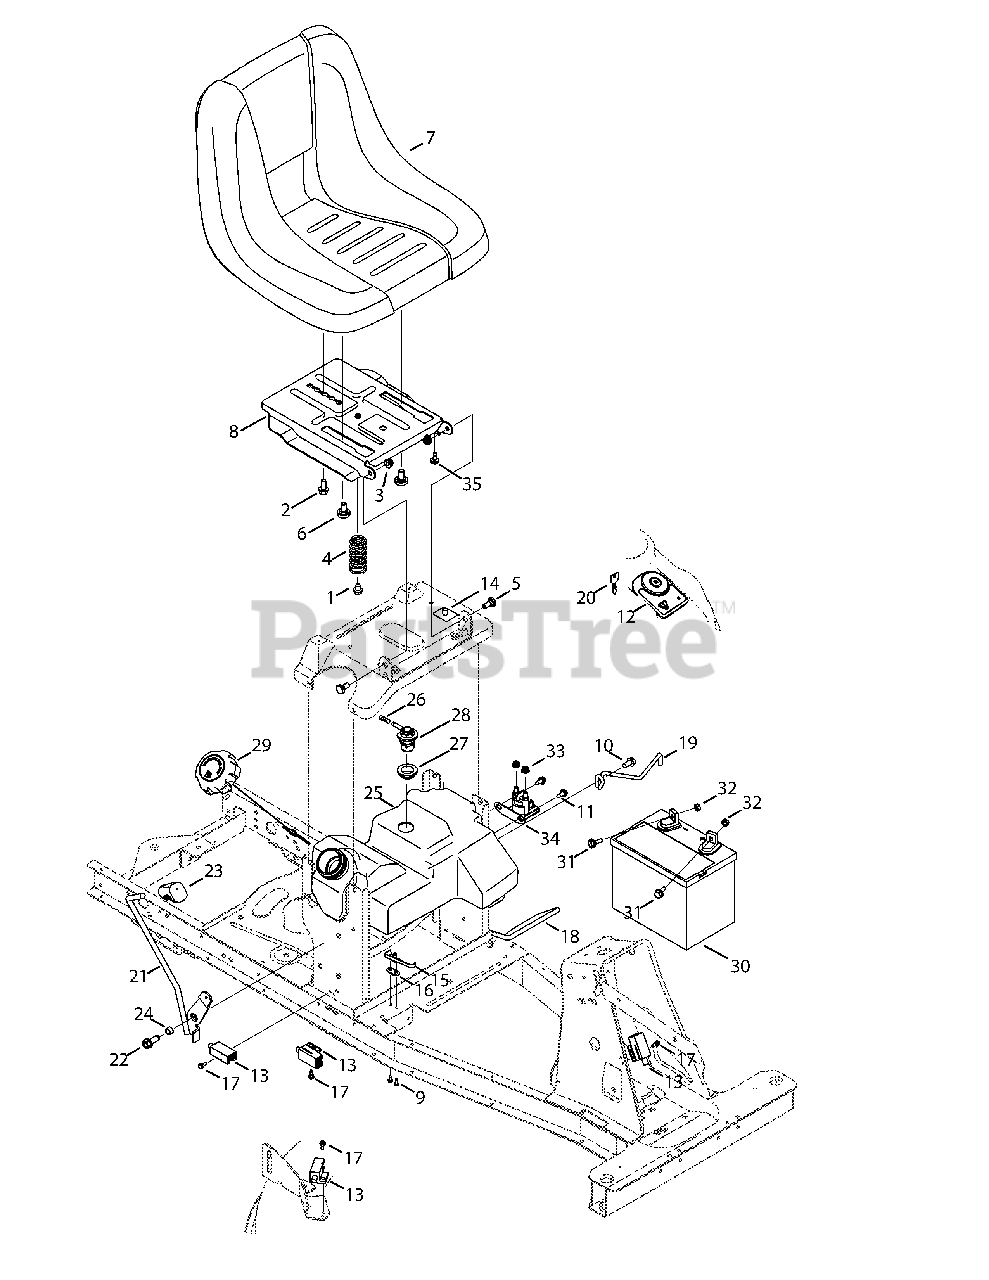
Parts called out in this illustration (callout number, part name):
1	Tap Screw, 5/16-18, 0.500
2	Hex Flange Screw, 3/8-16 x .75
3	Flange Lock Nut, 5/16-18
4	Seat Spring
5	Shldr Spacer, .435 X .178-5/16 X .56
6	Shoulder Screw, .625 x .145, 3/8-16
8	Seat Pivot Bracket
9	Screw, #8
10	Tap Screw, 5/16-18, .750
11	Tap Screw, 1/4-20, .625
12	Key Switch
13	Interlock Switch
14	Seat Switch
15	Switch Spring
16	Insulator Plate
17	Shoulder Screw, #10-32, .500
18	Battery Rod
19	Battery Hold Down Bracket
20	Key, Assembly
21	PTO Handle Assembly
22	Tap Screw, 3/8-16, 1.000
23	Handle Grip, 3/8
24	Spacer, .380 ID x .50 OD x .265
25	Fuel Tank, 1-3 Gal.
26	Hose Vent, 3/16 EPA
27	Rubber Grommet
28	Rollover Valve
29	Fuel Cap
30	Battery, 155 CCA
31	Screw, Shoulder, .250 x .150
32	Nut, Sems, 1/4-20
33	Flange Lock Nut, 1/4-20
34	Solenoid, 12v
35	Rubber Bumper, .63 Dia
